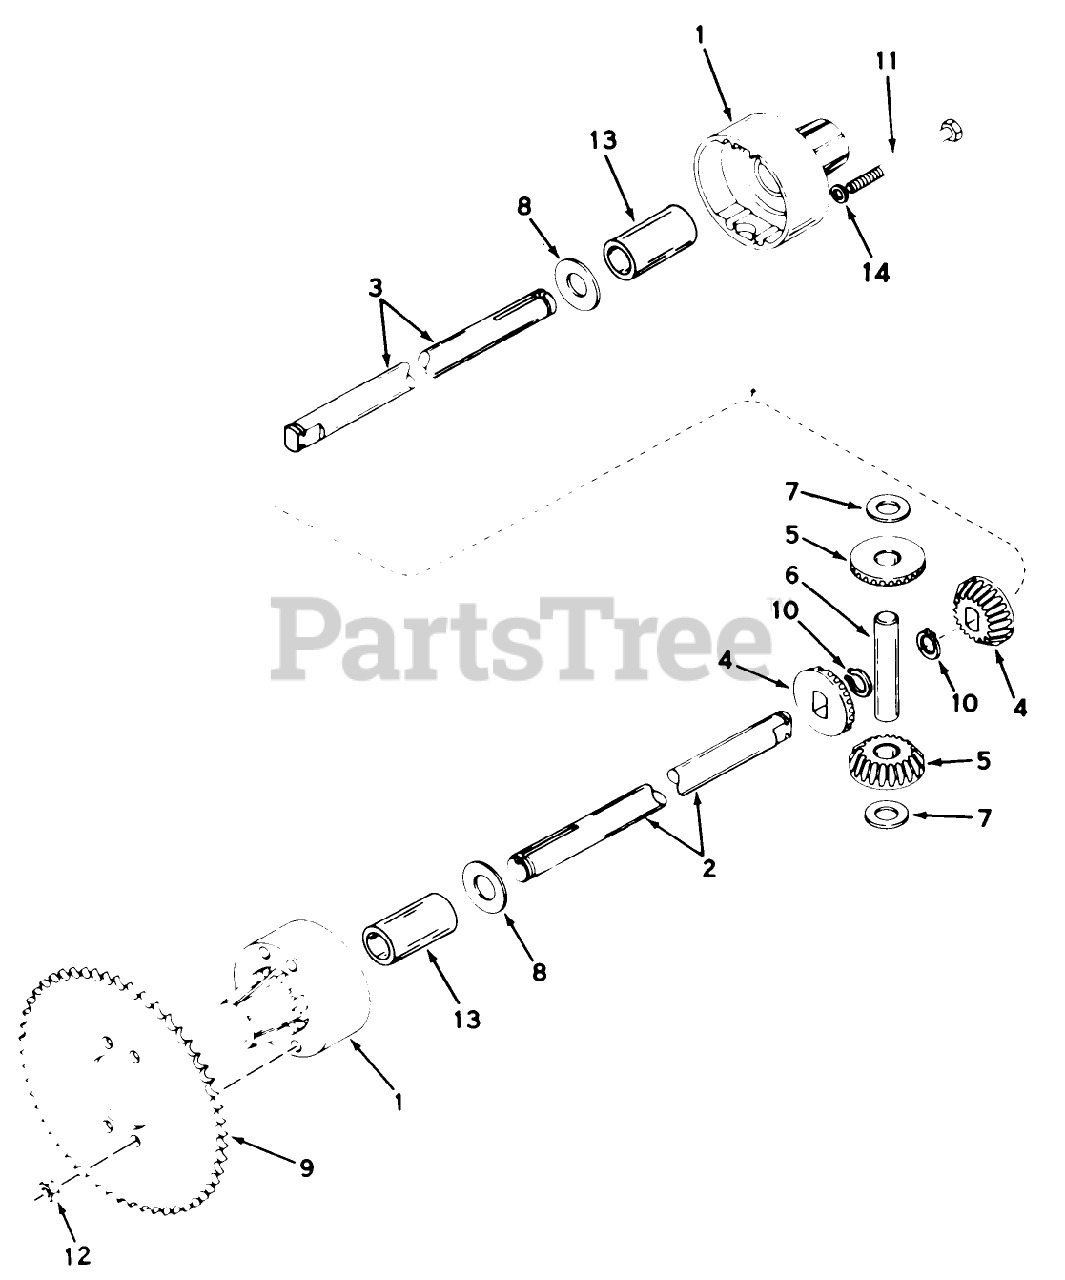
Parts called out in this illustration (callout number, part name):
1	Housing, Differential Carrier
4	Bevel Gear
5	Gear Pinion
6	Pin Drive
7	Washer Thrust
8	Washer
9	Sprocket (45 Tooth)
10	Ring-Snap
11	Screw-Hex Hd.
12	Nut-Lock
13	Bushing
14	Washer
